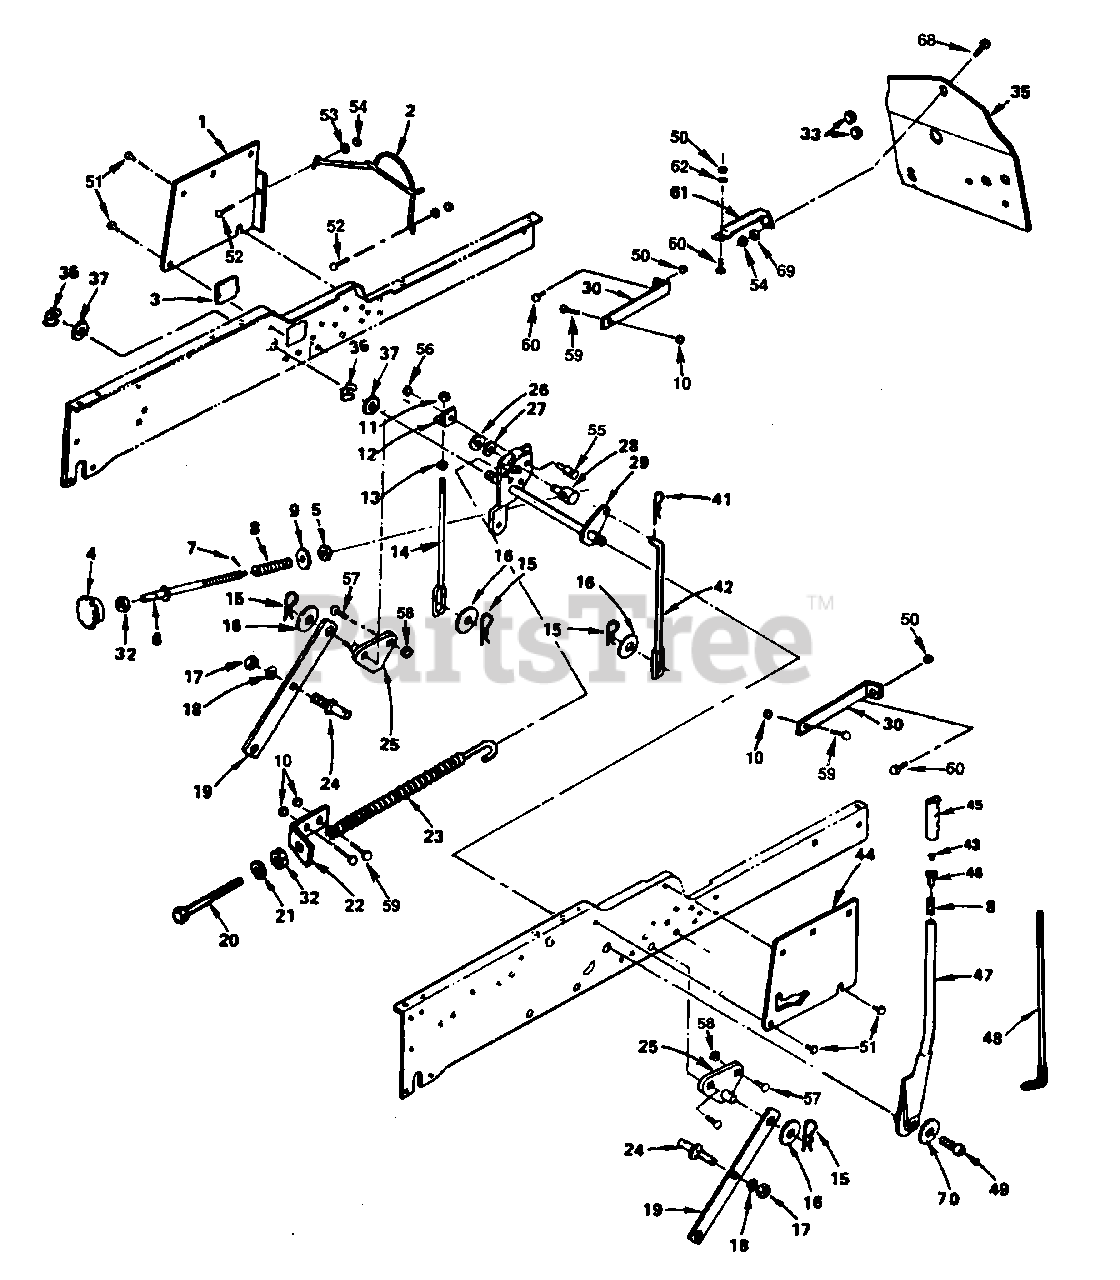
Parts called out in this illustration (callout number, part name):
1	L.H. Side Panel
2	Engine Belt Guard Assembly (AYP part number)
3	Access Cover (AYP part number)
4	Lift Adjust Handle (AYP part number)
5	Nut (AYP part number)
6	Lift Adjust Rod (AYP part number)
7	Cotter Pin (AYP part number)
8	Spring (AYP part number)
9	Washer (AYP part number)
10	Locknut
11	Hex w/Washer Locknut (AYP part number)
12	L.H. Lift Bracket (AYP part number)
13	Hex Nut 3/8-16 (AYP part number)
14	L.H. Link Lift (AYP part number)
15	Spring Retainer (AYP part number)
16	Washer (AYP part number)
17	Hex Nut (AYP part number)
18	Lock Washer (AYP part number)
19	Arm Suspension (AYP part number)
20	Assist Spring Adjust Bolt (AYP part number)
21	Washer 13/32 x 13/16 x 16 Ga. (AYP part number)
22	Assist Spring Bracket (AYP part number)
23	Lift Assist Spring (AYP part number)
24	Pivot Center Stud (AYP part number)
25	Suspension Bracket (AYP part number)
26	Klip Ring (AYP part number)
27	Washer (AYP part number)
28	Stop Depth Trunnion
29	Lift Shaft (AYP part number)
30	Heat Side Shield Bracket (AYP part number)
32	Hex Jam Nut (AYP part number)
33	Grommet (AYP part number)
35	Heat Shield Base
36	Klip Ring (AYP part number)
37	Washer (AYP part number)
41	Spring Retainer (AYP part number)
42	R.H. Lift Link (AYP part number)
43	Plunger Button (AYP part number)
44	R.H. Panel Side
45	Handle Grip (AYP part number)
46	Lift Lever Plunger (AYP part number)
47	Lift Lever Assembly (AYP part number)
48	Lever Rod Assembly (AYP part number)
49	Hex Bolt (AYP part number)
50	Locknut (AYP part number)
51	Washer Td. Hex Screw (AYP part number)
52	Carriage Bolt 5/16-18 x 1 (AYP part number)
53	Washer (AYP part number)
54	Locknut
55	Shoulder Bolt (AYP part number)
56	Hex Flange Nut
57	Carriage Bolt 3/8-16 x 3/4 (AYP part number)
58	Centerlock Nut (AYP part number)
59	Hex Bolt 3/8-16 x 1 (AYP part number)
60	Hex Bolt (AYP part number)
61	Heat Shield Brace
62	Washer (AYP part number)
68	Hex Bolt 5/16-18 x 3/4 (AYP part number)
69	Washer (AYP part number)
70	Lock Washer (AYP part number)
